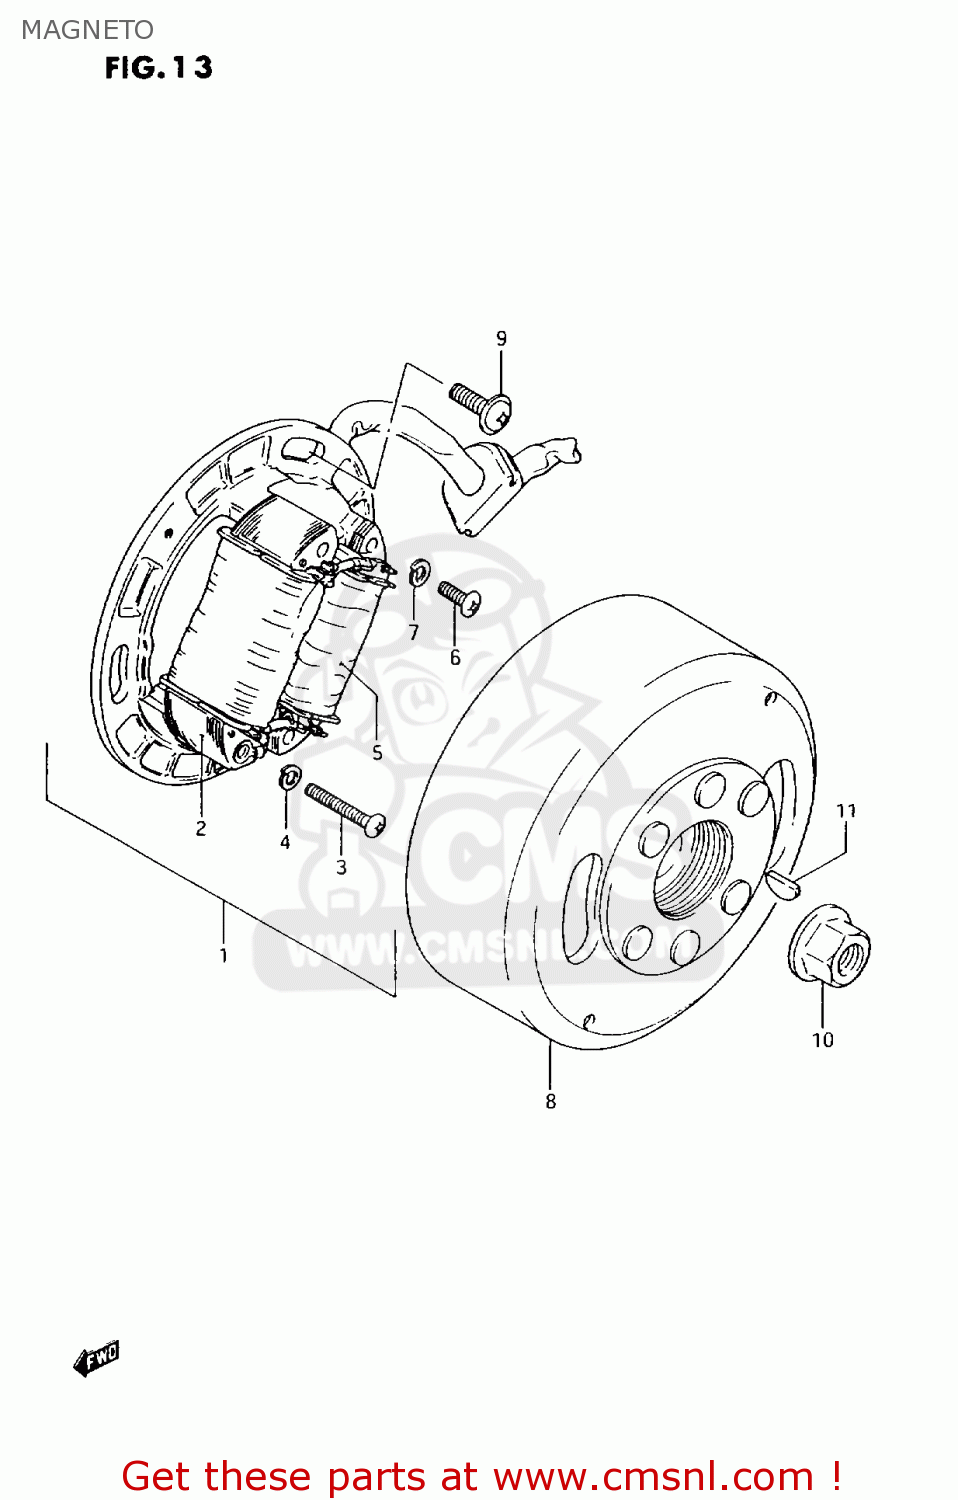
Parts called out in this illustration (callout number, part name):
1	STARTER ASSY
2	COIL,LIGHTING
3	SCREW(4X30)
4	WASHER,LOCK
5	COIL,PRIMARY
6	SCREW 4X16
7	WASHER,LOCK
8	ROTOR, FRYWHEEL
9	SCREW 5X12
10	NUT
11	KEY
